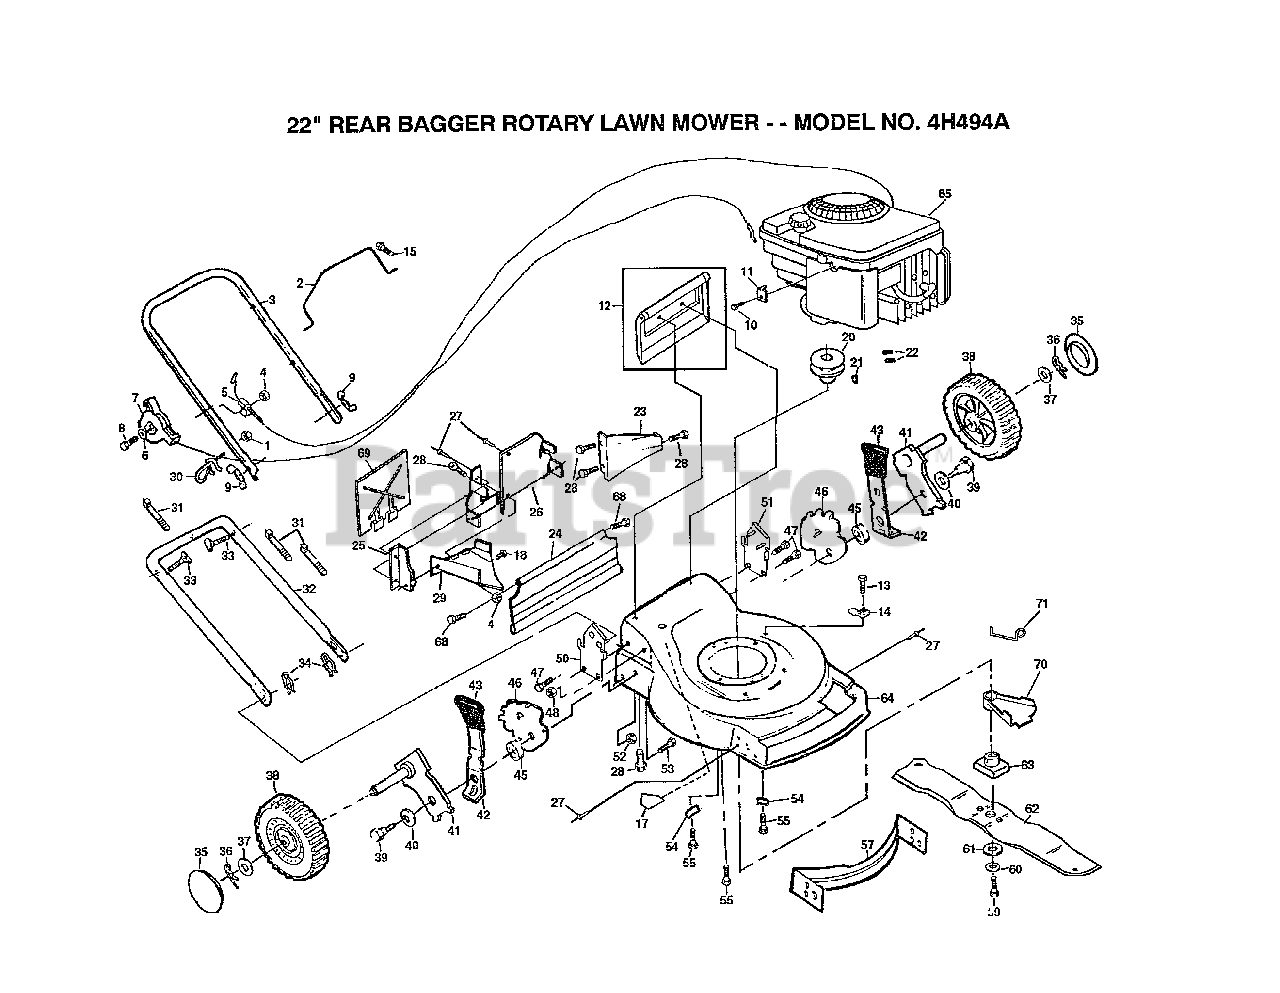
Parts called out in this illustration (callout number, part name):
1	NUT
2	CONTROL BAR
5	"CABLE,ENG ZONE CO"
6	WASHER PM
7	"CONTROL, THROTTLE"
9	"NUT,WING PM"
10	SCREW PM
11	CABLE CLAMP
13	TAPPING SCREW
14	GUIDE CLIP PM
15	"SCREW,PAN HD"
17	DECAL HYT
18	SCREW PM
20	ENGINE.PULLEY.FWG
21	HI PRO KEY PM
22	SCREW
23	REAR BAFFLE
27	BLIND RIVET
28	SCREW
29	DISCHARGE BAFFLE
30	ROPE GUIDE
33	BOLT.HANDLE.LM
34	HAIRPIN COTTER
35	HUB CAP
36	RETAINER CLIP PM
37	WASHER
40	"WASHER, BELLEVIL."
41	AXLE ARM
43	KNOB PM
47	SCREW
52	LOCKNUT PM
55	SCREW
59	SCREW
60	LOCKWASHER
61	"WASHER,HARDEN"
63	ADAPTOR.BLADE.LM
68	HINGE SCREW
69	MULCHER PLATE
71	DEBRIS SHLD RET
